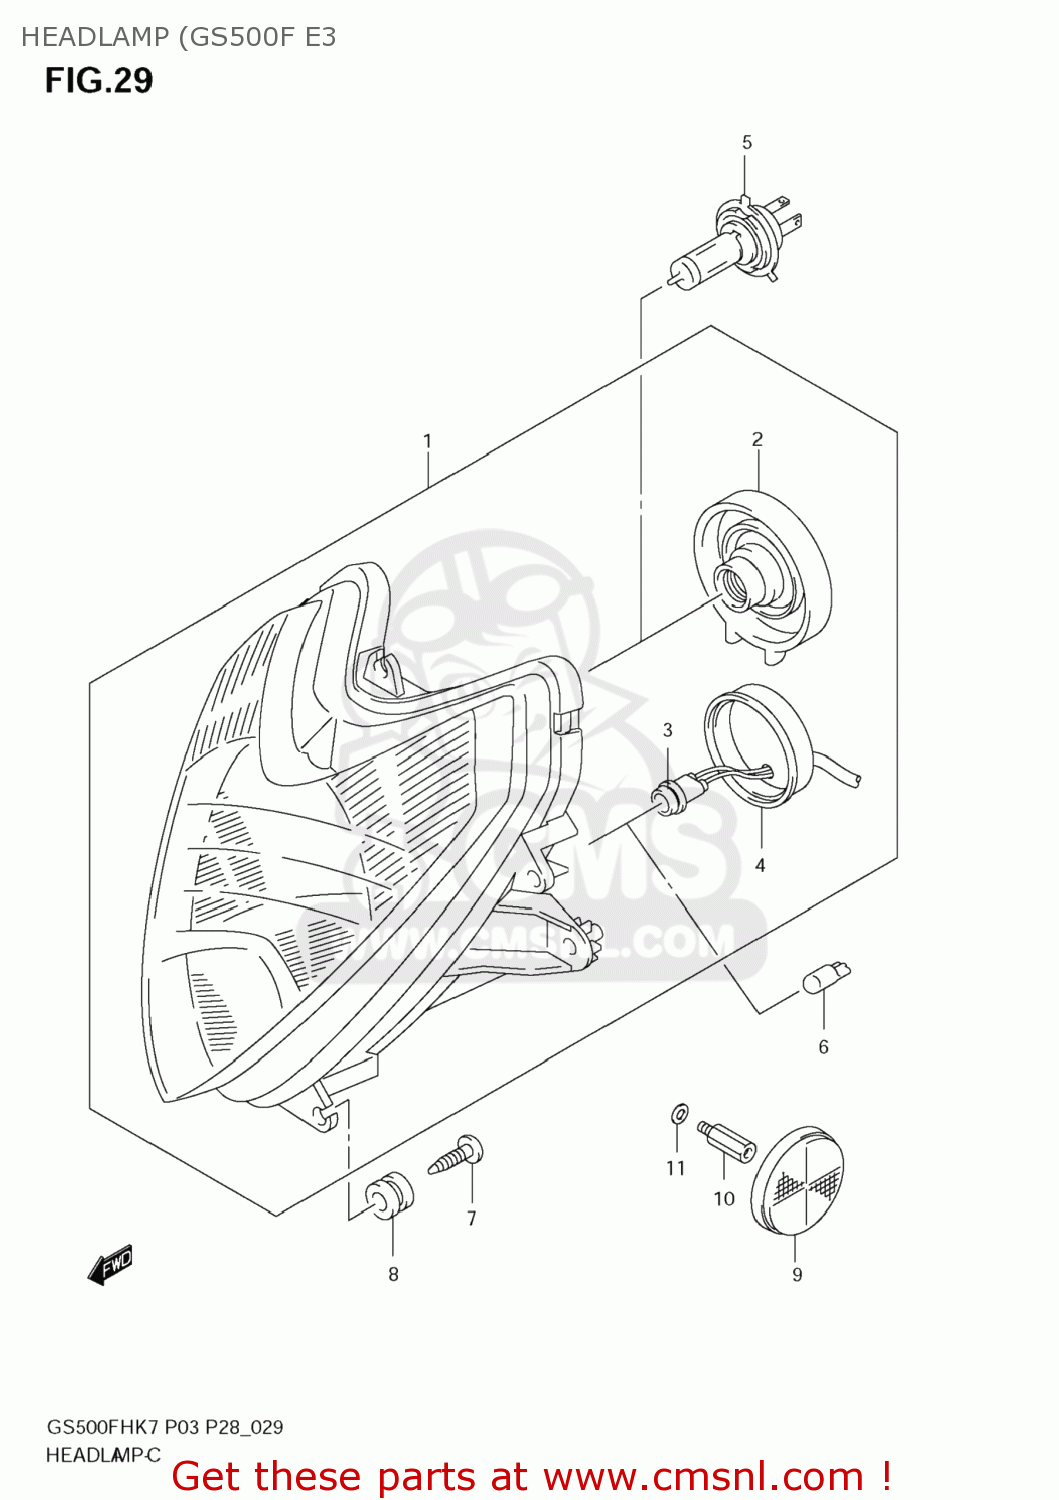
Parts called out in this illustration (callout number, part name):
1	HEADLAMP ASSY
2	COVER, SOCKET
3	COVER
5	BULB(12V60/55W,H4)
6	BULB(12V5W)
7	SCREW(5X15)
8	CUSHION
9	REFLECTOR,REFLEX
10	BOLT(5X10)
11	WASHER
